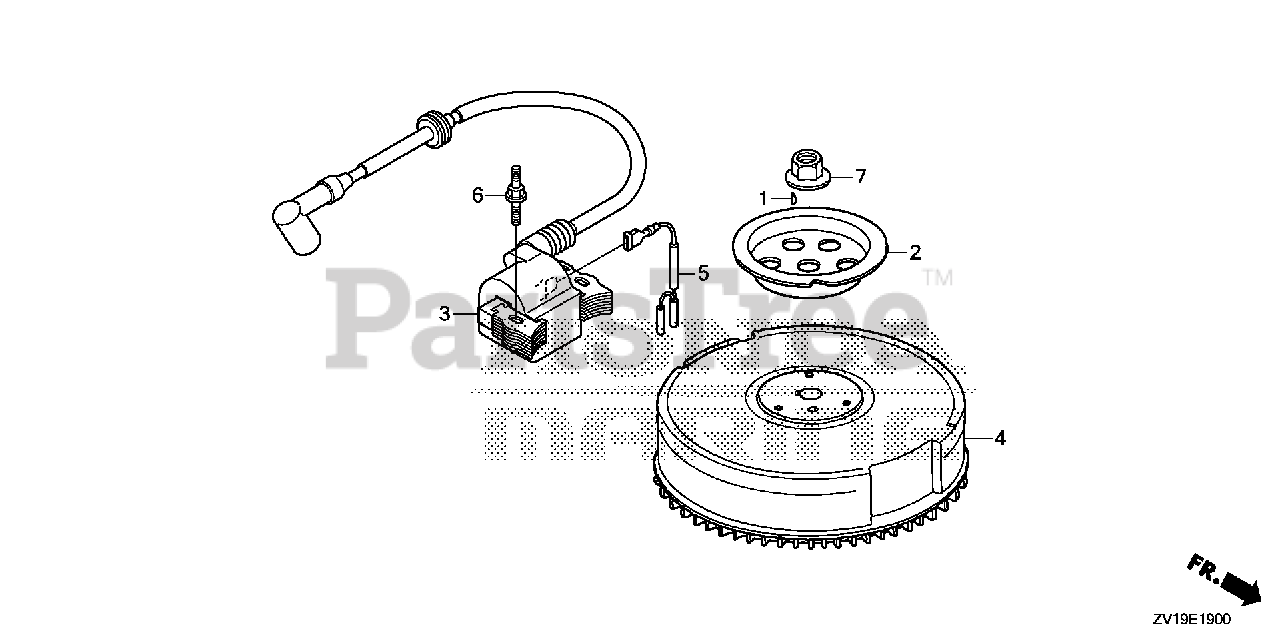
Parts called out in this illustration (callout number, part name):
1	KEY, SPECIAL WOODRUFF (25X18)
2	PULLEY, STARTER
3	COIL ASSY., IGNITION
4	FLYWHEEL *TBLACK* (BLACK)
5	WIRE, STOP SWITCH
6	BOLT, SPECIAL (6MM)
7	NUT, SPECIAL (14MM)
